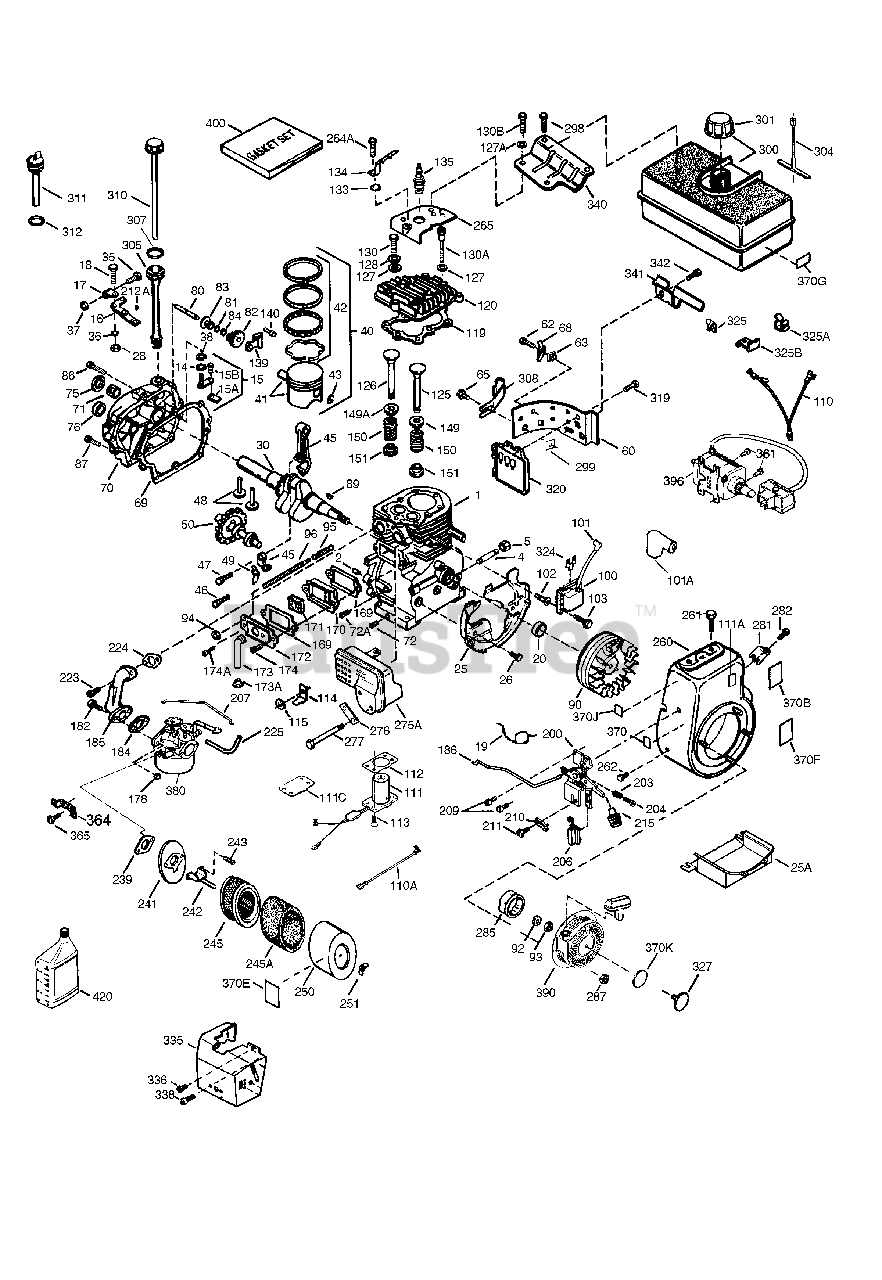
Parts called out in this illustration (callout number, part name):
1	"Cylinder Ass'y. (Incl. 2, 20, 72 & 72 A)(3-1/8" Bore)
2	Dowel Pin
14	Flat Washer
15	Governor Rod (Incl. 15A & 15B)
15A	Governor Yoke
15B	Screw, 6-40 x 5/16"
16	Governor Lever Ass'y. (Incl. 212A)
17	Governor Lever Clamp
18	Screw, T-15, 8-32 x 3/8"
19	Extension Spring
20	Oil Seal
25	Blower Housing Baffle
26	Screw, 1/4-20 x 19/32"
28	Lock Nut, 8-32
30	Crankshaft
35	Screw, 10-32 x 3/4"
36	Lock Washer #8
37	Lock Nut, 10-32
38	Retaining Ring
40	Piston, Pin & Ring Set (Std.)
40	Piston, Pin & Ring Set (.010" OS)
41	Piston & Pin Ass'y (Std.) (Incl. 43)
41	Piston & Pin Ass'y (.010" OS) Incl. 4 3
42	Ring Set (Std.)
42	Ring Set (.010" OS)
43	Piston Pin Retaining Ring
45	Connecting Rod Ass'y (Incl. 47 & 49)
47	Connecting Rod Bolt
48	Valve Lifter
49	Oil Dipper
50	Camshaft (MCR)
60	Blower Housing Extension
69	* Cylinder Cover Gasket
70	Cylinder Cover Incl. 74,75,80-84,175 &176
72	Oil Drain Plug (Sq. hd., 1/4-18)
75	Oil Seal
80	Governor Shaft
82	Governor Gear Ass'y. (Incl. 81)
83	Governor Spool
84	Retaining Ring
86	Screw, 1/4-20 x 1-3/16"
87	Screw, 1/4-20 x 1-11/16"
89	Flywheel Key
90	Flywheel
92	Lock Washer
93	Flywheel Nut
100	Solid State Ignition (Incl. 101)
101	Spark Plug Cover
102	Solid State Mounting Stud
103	Screw, T-15, 10-24 x 15/16"
119	* Cylinder Head Gasket
120	Cylinder Head
125	Exhaust Valve (Std.)(Incl. 151)
125	Exhaust Valve (1/32" OS) (Incl. 151)
126	Intake Valve (Std.) (Incl. 151)
128	Belleville Washer
130	Screw, 5/16-18 x 2"
130A	Screw, 5/16-18 x 17/32"
135	Resistor Spark Plug - RJ17LM
139	Governor Gear Bracket
140	Screw, 10-24 x 1/2"
149	Valve Spring Cap
150	Valve Spring
151	Valve Spring Keeper
151A	Valve Spring Cap
169	* Valve Cover Gasket
170	Breather Body
171	Breather Element
172	Valve Cover
173	Breather Tube
173A	Breather Tube Grommet
174	Screw, 10-24 x 1/2"
178	Nut & Lock Washer 1/4-28
182	Screw, 1/4-28 x 1"
184	* Carburetor To Intake Pipe Gasket
185	Intake Pipe
186	Governor Link
200	Control Bracket (Incl. 203 & 204)
203	Compression Spring
204	Screw, T-10, 5-40 x 7/16"
207	Choke Link
210	Conduit Clip
211	Screw, 10-32 x 3/8"
212A	Bushing
223	Screw, T-30, 5/16-18 x 1-3/32"
224	* Intake Pipe Gasket
239	* Air Cleaner Gasket
242	Air Cleaner Base
245	Air Filter
245A	Air Filter (Poly)
250	Air Cleaner Cover
251	Wing Nut, 1/4-20
260	Blower Housing
261	Screw, 5/16-18 x 3/4"
262	Screw, T-40, 5/16-24 x 21/32"
264A	Screw, 1/4-20 x 5/8"
265	Cylinder Head Cover
276A	Locking Plate
277	Screw, 5/16-18 x 3-3/16"
285	Starter Cup
298	Screw, 1/4-15 x 3/4"
300	Fuel Tank (Incl. 292 & 301) (Outlet o n Right-Side)
301	Fuel Cap
305	Oil Fill Tube
307	"O" Ring
308	Fill Tube Clip
310	Dipstick
319	Screw, 10-24 x 3/8"
320	Regulator
323A	Terminal
323B	Terminal
327	Starter Plug
338	Screw, 10-32 x 1/2"
340	Fuel Tank Bracket
341	Fuel Tank Bracket
370	Decal - Important Lubrication - SAE 3
370	Decal - XL/C Industrial/Commercial
370	Decal - XL/C industrial/Commercial Wi th Air Filter Service Info
380	Carburetor (Incl. 184)
390	Rewind Starter NOTE: This engine cou ld hav e been built with 590704 start er.
400	* Gasket Set (Incl. items marked PK in notes) Incl. part #'s 27272A (1)27896 A (2),27915A (1),29673 (1),33263 (1), 33629 (1), 34698A (1),35317 (1),35967 A (1), 36448 (1), 37342 (1)
420	SAE 30 4-Cycle Engine Oil (Quart)
702	Screw, 5/16-18 x 1-3/4"
